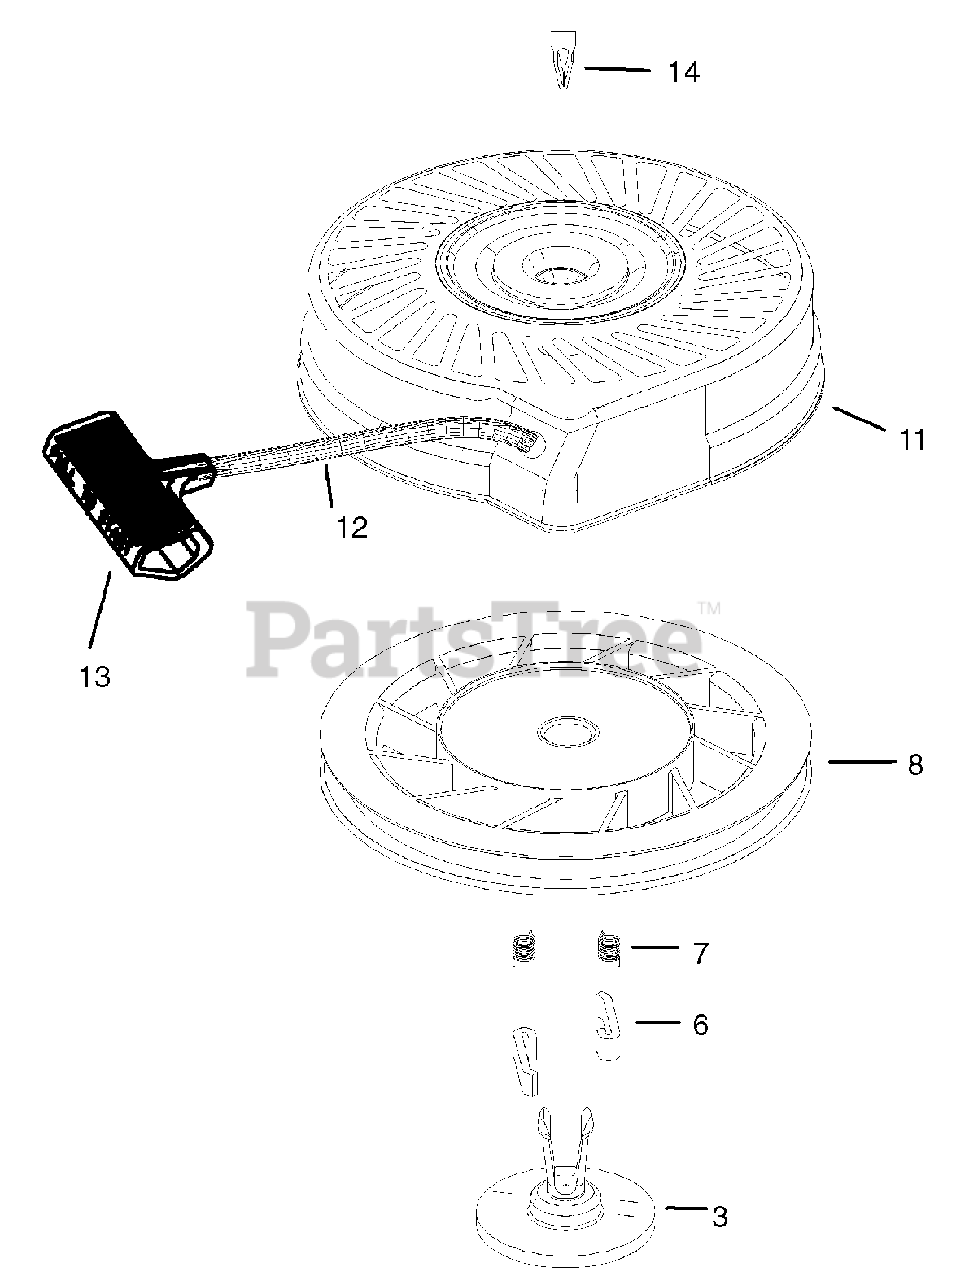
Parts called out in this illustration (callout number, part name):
3	Retainer
6	Starter Dog
7	Dog Spring
8	Pulley & Rewind Spring ASM
11	Starter Housing ASM (40 degree grommet)
12	Starter Rope (Length 98" x 9/64" dia.)
13	Starter Handle
14	Spring Clip
